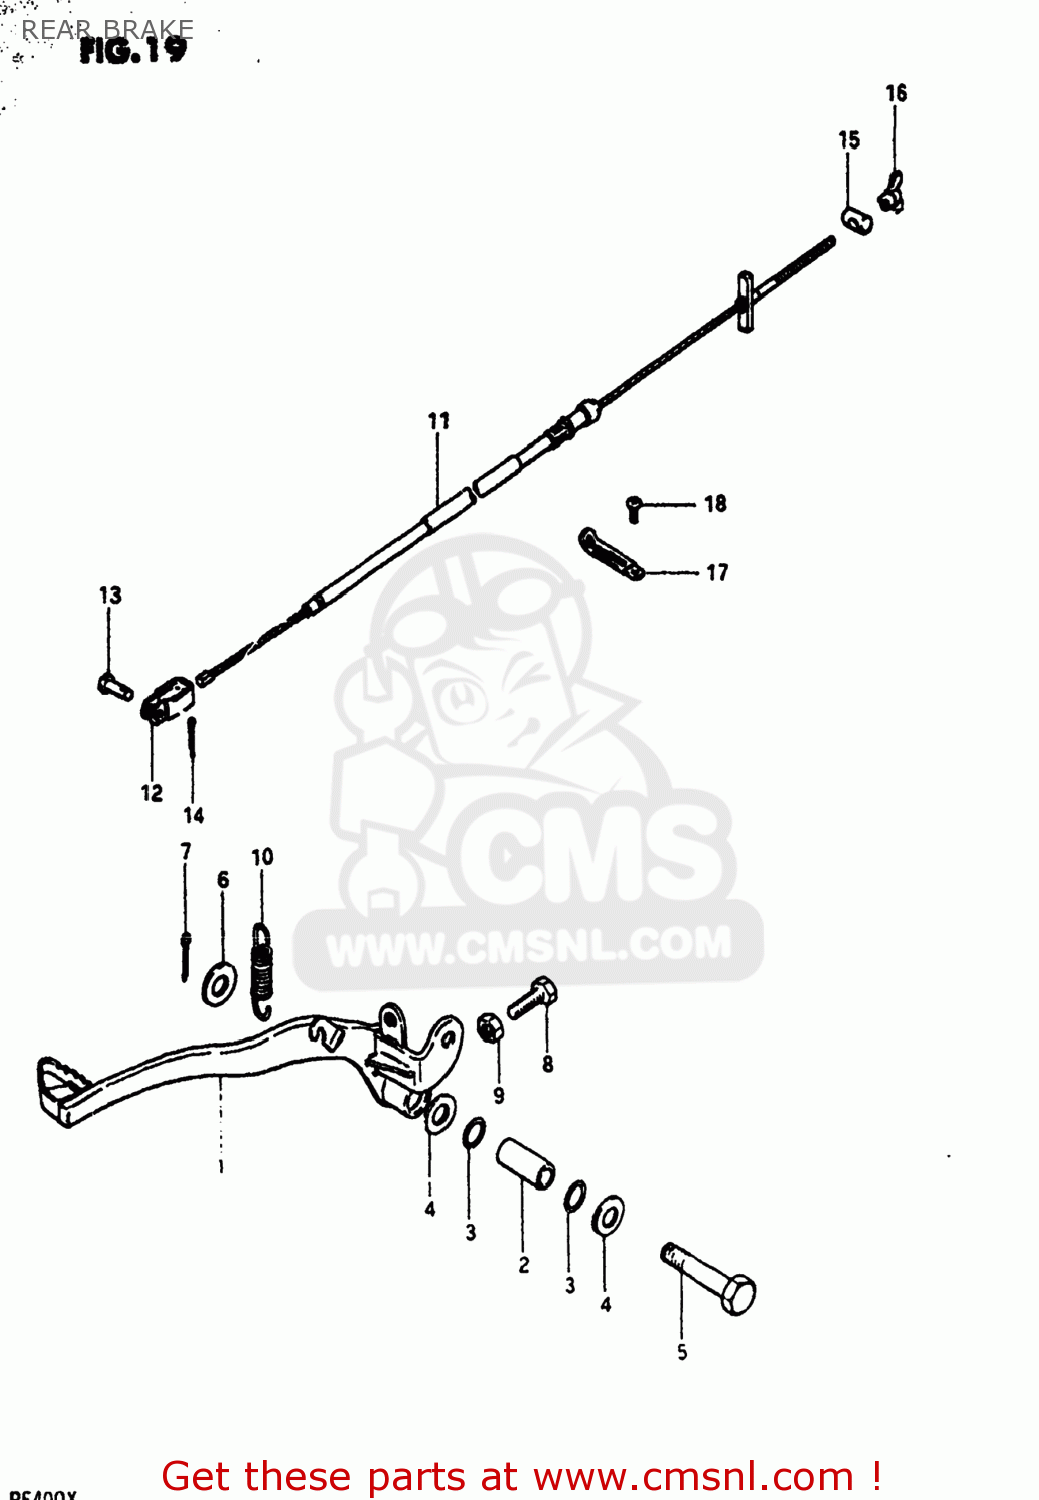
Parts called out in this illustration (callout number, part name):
1	PEDAL,BRAKE
2	SPACER (8X10X22)
3	O-RING (D:1.5 ID:10)
4	WASHER
5	BOLT 8X43.5
6	WASHER
7	PIN 20X20
8	BOLT 6X25
9	NUT
10	SPRING
11	CABLE,RR BRAKE
12	HOOK,REAR BRAKE PEDAL
13	PIN(L:13)
14	PIN
15	PIN
16	NUT
17	CLAMP
18	SCREW,6X6
